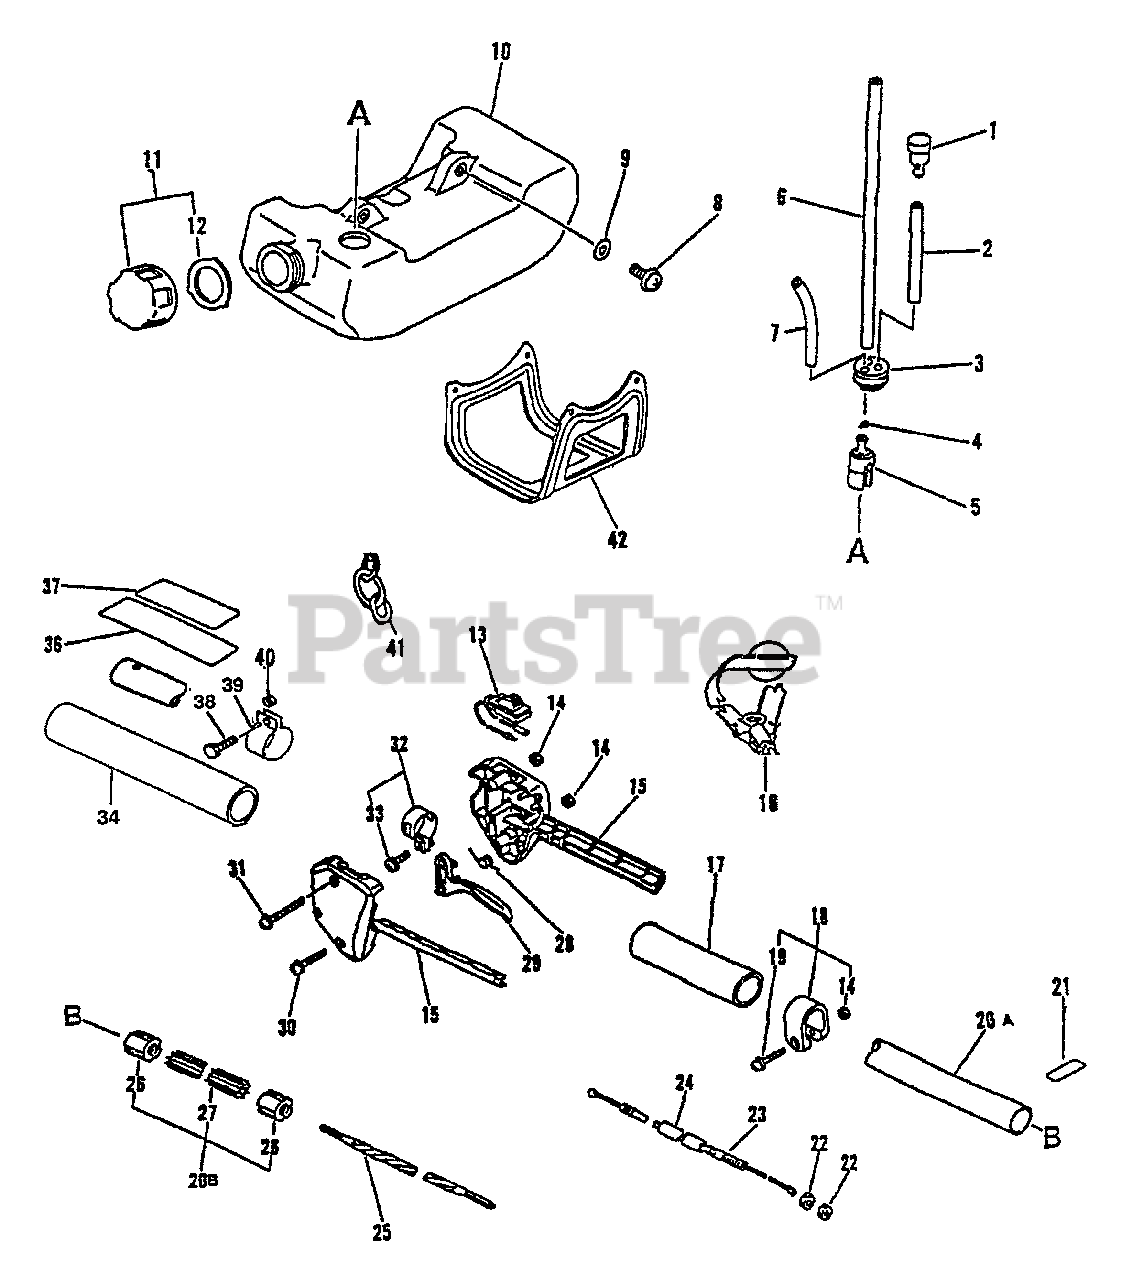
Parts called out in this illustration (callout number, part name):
1	VENT, FUEL TANK
2	PIPE - 3X5X70 -- BLACK
3	GROMMET
4	CLIP - 6
5	FILTER, FUEL
6	PIPE - 3X5X180 -- BLACK
7	PIPE - 3X6X90 -- CLEAR
8	SCREW - 5X16
9	WASHER - 5
10	TANK, FUEL
11	CAP ASSY
12	GASKET, CAP
13	IGNITION SWITCH ASSY
15	CONTROL HANDLE KIT
16	SHOULDER STRAP ASSY
17	GRIP, HANDLE
18	CLAMP KIT
19	SCREW - 5X28
20	MAIN PIPE ASSY
21	LABEL - ALIGNMENT
23	CABLE, THROTTLE
24	TUBE - VINYL
25	DRIVESHAFT - FLEXIBLE
27	LINER - FLEXIBLE
28	SPRING, TRIGGER
29	TRIGGER, THROTTLE
30	SCREW - 5X25
31	SCREW - 5X35
32	CLAMP KIT
33	SCREW - 5X14
34	GRIP, HANDLE
36	LABEL - CAUTION
37	LABEL - CAUTION
38	BOLT - 5X18
42	GUARD, FUEL TANK
